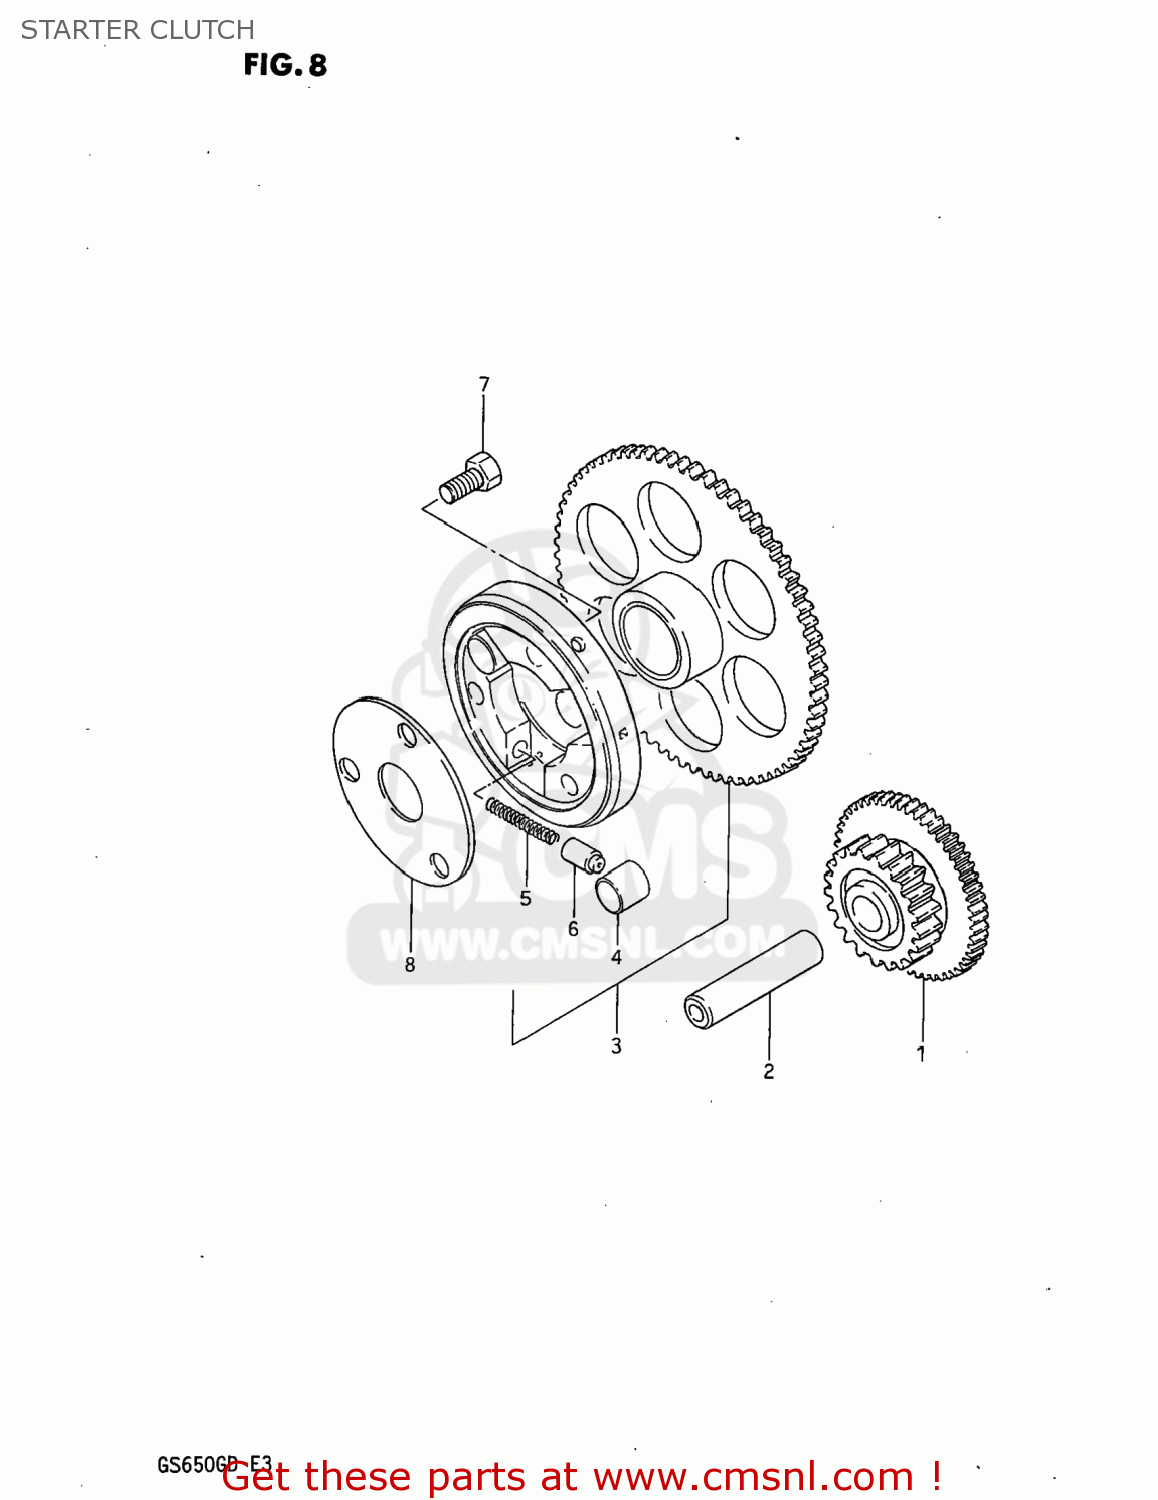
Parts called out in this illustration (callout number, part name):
1	GEAR,STARTER IDLE
2	PIN(7.4X13X56)
3	CLUTCH SET,STARTER
4	ROLLER(15X13)
5	SPRING
6	PIECE,PUSH
7	BOLT
8	SHIM,STARTER CLUTCH HUB
